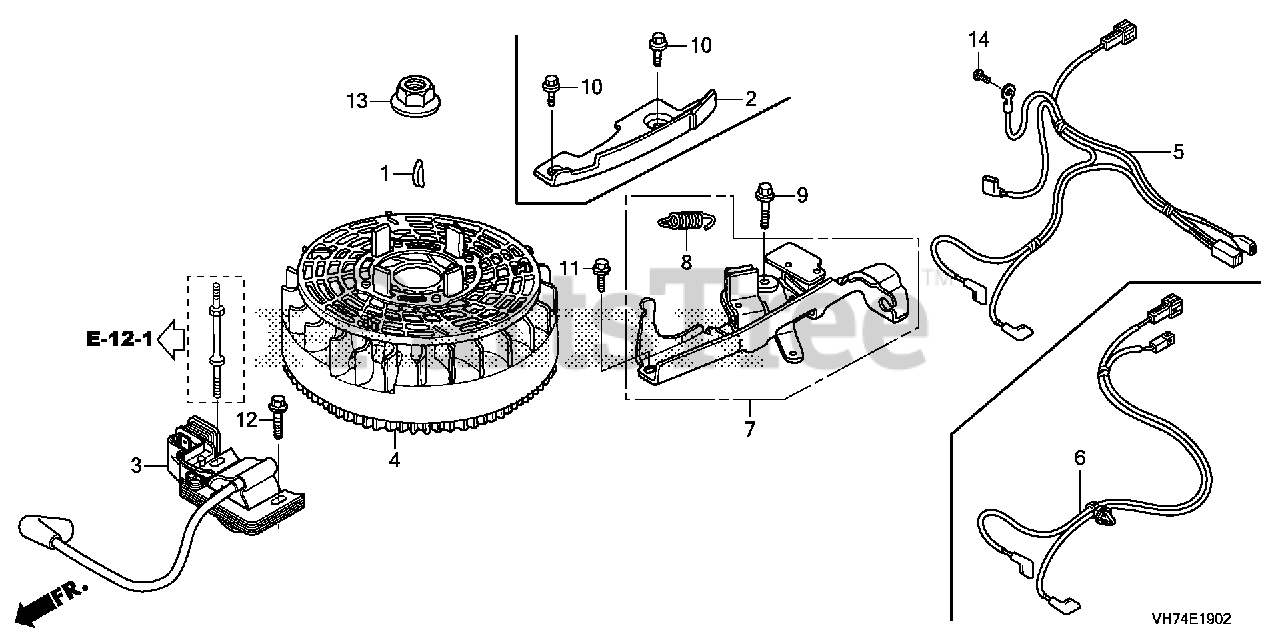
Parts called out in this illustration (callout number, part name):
1	KEY, SPECIAL WOODRUFF (25X18)
3	COIL ASSY., IGNITION
4	FLYWHEEL ASSY.
5	WIRE, COMBINATION
7	BRAKE SUB-ASSY.
8	SPRING, BRAKE LEVER
9	BOLT, FLANGE (6X23) (CT200)
11	BOLT, FLANGE (6X14)
12	BOLT, FLANGE (6X23)
13	NUT, FLANGE (14MM)
14	SCREW, PAN (5X8)
